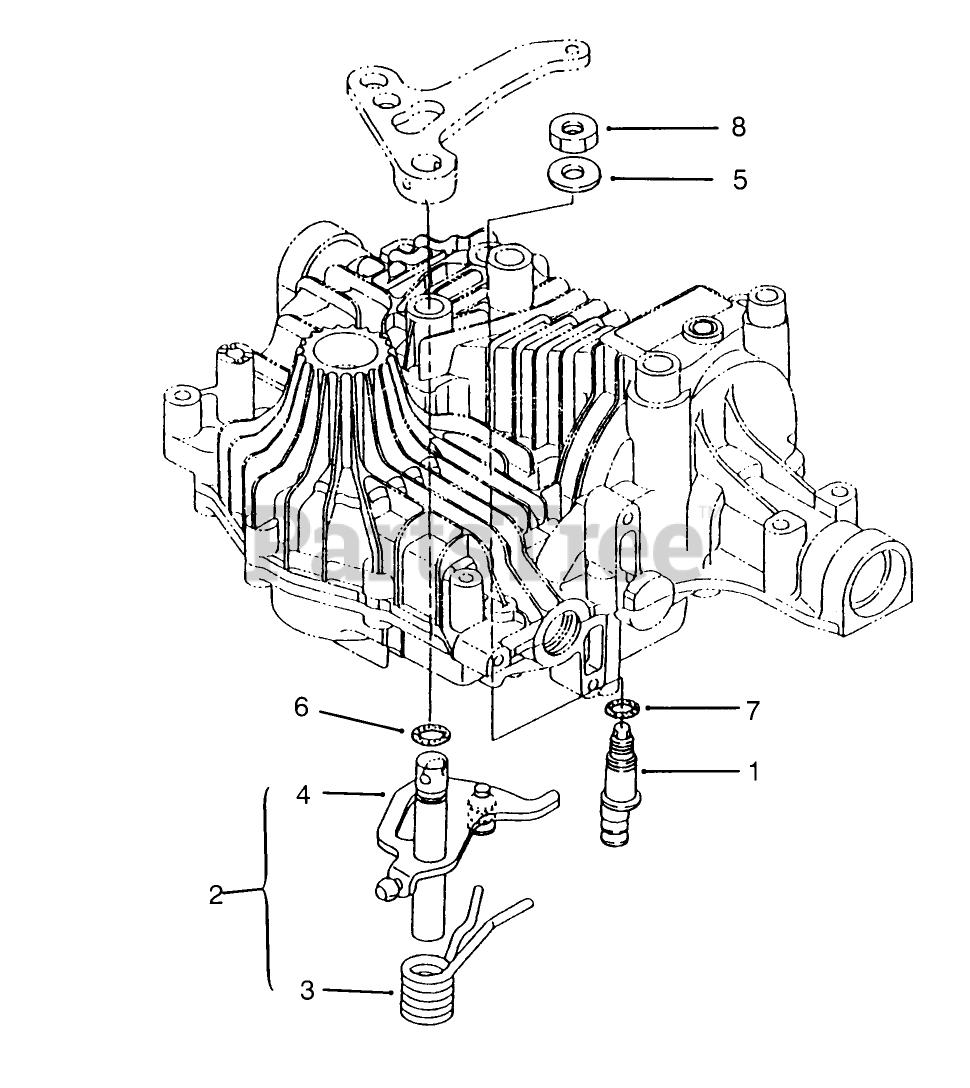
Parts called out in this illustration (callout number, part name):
1	FULCRUM
5	WASHER
6	O-RING
7	PACKING
